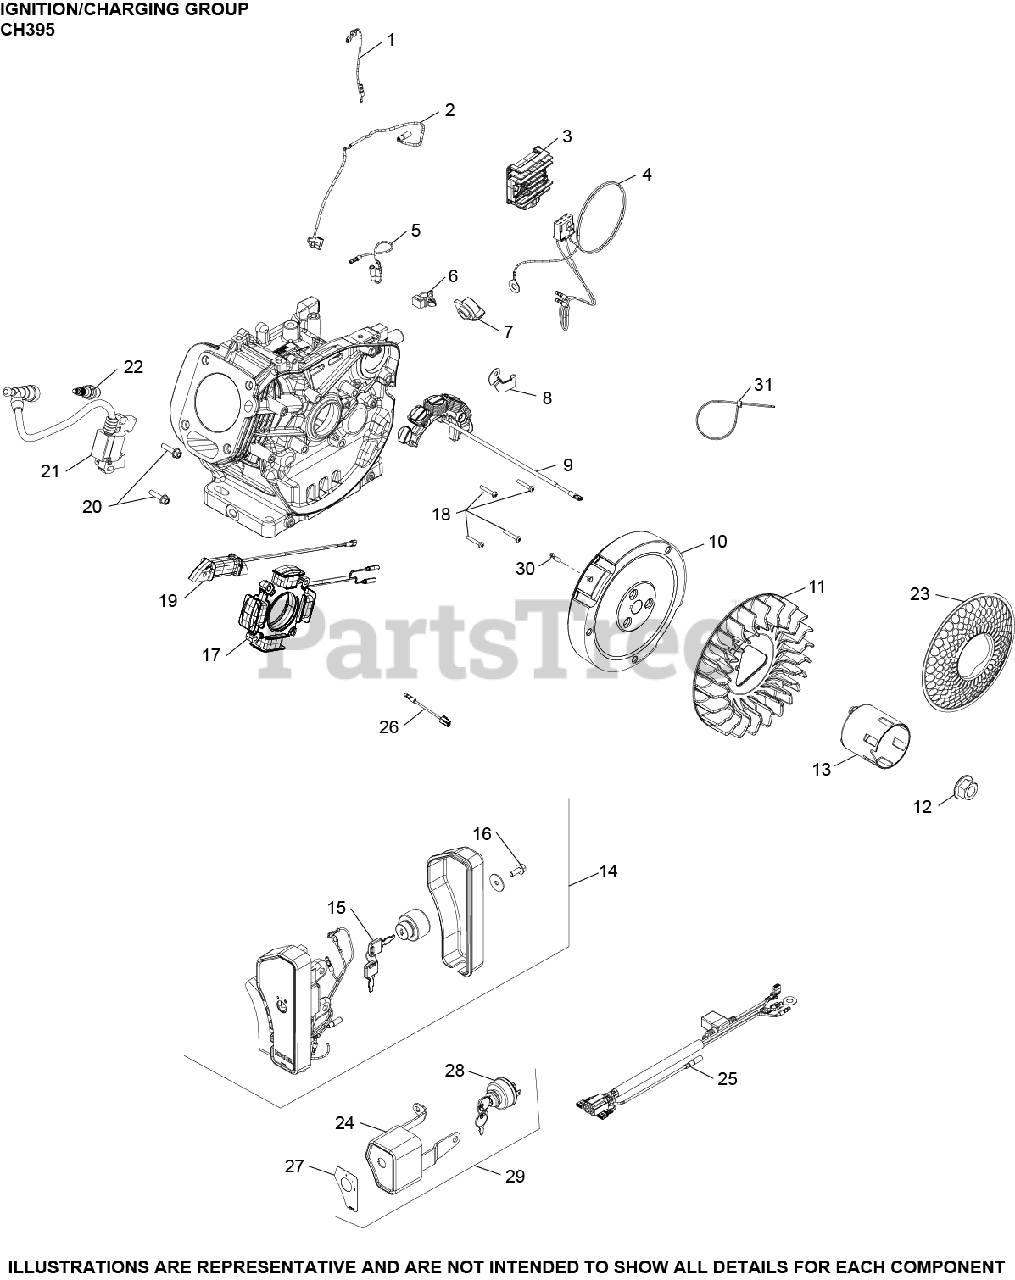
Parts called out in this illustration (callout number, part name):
2	LEAD, GROUND TO KILL
6	CLIP, WIRE HARNESS
8	BRACKET, STATOR WIRE
9	STATOR ASSEMBLY, 10A
10	FLYWHEEL ASSY ELECTRIC START (CH395)
11	FAN, FLYWHEEL
12	NUT, FLYWHEEL
13	CUP, STARTER DRIVE
14	KEY BOX ASSY W/HARNESS AND SWITCH
15	KEYS FOR SWITCH
16	SCREW, HEX FLANGE (M6)-USE 25 086 433-S
18	SCREW, STATOR MOUNTING (CKY)
20	SCREW, M6 X 25 USE 25 086 436-S
21	MODULE, SPARK PLUG ASSY
22	PLUG, SPARK (STD)
24	KEYBOX HOUSING
25	HARNESS, WIRING ASSEMBLY (10 AMP)
27	LABEL, KEY BOX
28	SWITCH, KEY ASSEMBLY USE 25 099 37-S
29	KIT, KEY BOX ASSEMBLY
